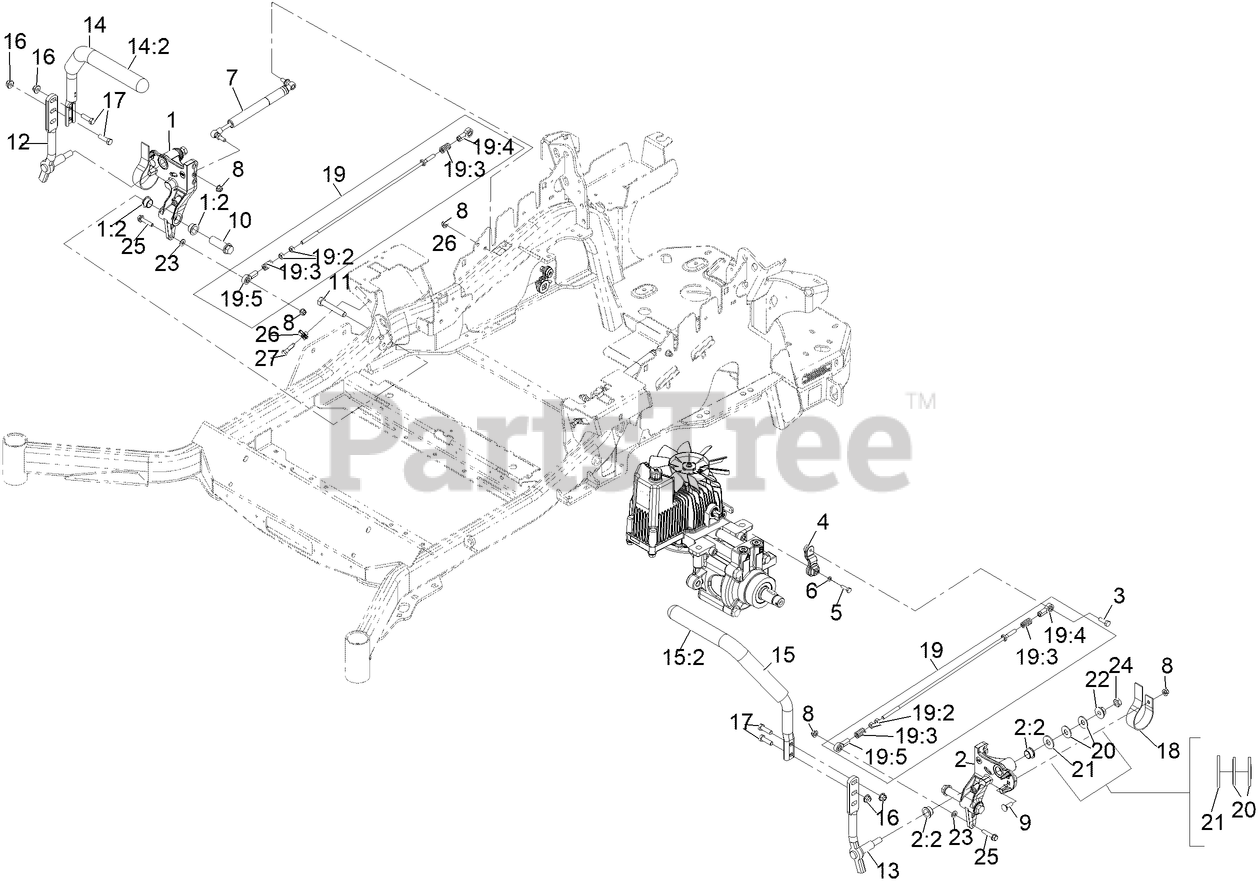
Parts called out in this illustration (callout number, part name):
1	RH MOTION CONTROL AND BUSHING ASM
1:2	BUSHING-FLANGE
2	LH MOTION CONTROL AND BUSHING ASM
2:2	BUSHING-FLANGE
3	SCREW-HH, THREAD LOCKING
4	ARM-CONTROL, PUMP
5	SCREW-HH
6	WASHER-SPRING
7	DAMPER-CONTROL, MOTION
8	NUT-HF, NI
9	BOLT-CARR
10	HUB-THREADED
11	SCREW-HH
12	LEVER-CONTROL MOTION, RH
13	LEVER-CONTROL MOTION, LH
14	RH HANDLE ASM
14:2	GRIP-LEVER, CONTROL
15	LH HANDLE ASM
15:2	GRIP-LEVER, CONTROL
16	NUT-HF, NI
17	SCREW-HH
18	SPRING-LEAF
19	FRONT PUMP LINKAGE ASM
19:2	NUT-HEX
19:3	SPRING-COMPRESSION
19:4	BALLJOINT-LH
19:5	BALLJOINT-RH
20	WASHER-SPRING
21	WASHER-FLAT
23	WASHER-PLAIN
24	NUT-JAM
25	SCREW-HHF
27	SCREW-HH,LOCK
